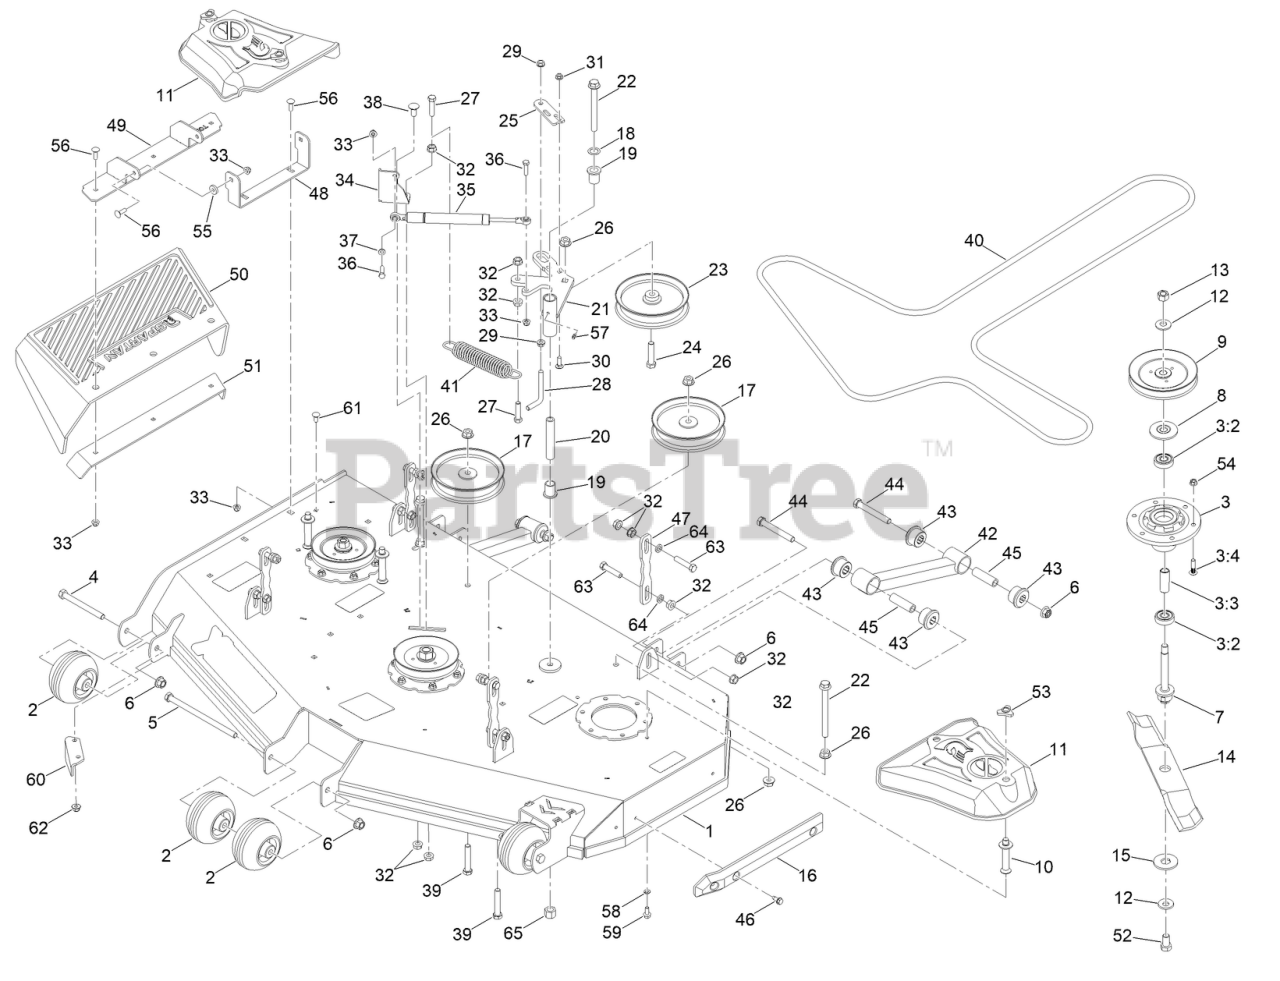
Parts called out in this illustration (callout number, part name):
1	54 INCH DECK ASM W/DECALS
2	MWR ANTI-SCALP WHL W/O GREASE FITTING
3	SPINDLE ASM 5IN DECK
3:2	BEARING
3:3	SPACER, BEARING
3:4	BOLT-ROUND HEAD
4	SCREW-HH
5	1/2-13 X 8-1/2 HEX C/S GR 2 ZINC YELLOW
6	NUT-LOCK
7	SHAFT - SPINDLE
8	GUARD-BEARING TOP 0.673IN
9	PULLEY
10	PIN-BELT COVER
11	COVER BELT
12	M16 SPRING WASHER (39MMOD/ 3.9MM THK)
13	M16X1.5 C8.8 HEX NUT
14	BLADE-ROTARY
15	WASHER-HEX
16	MWR NYLON DECK GUARD
17	6-3/4IN IDLER PULLEY 15/16IN SPACER ASSY
18	.767IDX1.125ODX.016 THK TRIP WV WASHER
19	3/4IN ID X15/16IN OD X 1-1/8IN FLNG BUSH
20	MWR INNER IDLER SPACER
21	MWR DECK IDLER PULLEY ARM ASSY PAINT
22	1/2-13 X 5-1/2 HEX FLANGE BOLT GR 8 ZY
23	6-3/4IN IDLER PULLEY 7/16IN SPACER ASM
24	SCREW-HH
25	DECK IDLER PULLEY BELT RETNR BRKT PAINT
26	NUT-HHF
27	SCREW-HH
28	BOLT-L
29	3/8-16 HEX FLANGE NUT W/SERR ZINC YELLOW
30	BOLT-CARR
32	NUT-HF
33	NUT-HF, NI
34	DECK BELT IDLER DAMPER MTG BRKT PAINTED
35	IDLER GAS SPRING
36	SCREW-HH
37	.312IDX.625ODX.062 THK THRUST BRG OI BRZ
38	SCREW-CARR
39	1/2-13 X 2-3/4 HEX FLANGE BOLT (GR.8) YZ
40	54 DECK BELT
41	MWR DECK SPRING
42	RZ MWR DECK STABLZR ASSY
43	RED A80 SUSP BUSHING
44	1/2-13 X 3-3/4 HEX C/S (GR.5) ZC/YEL
45	UTV A-ARM BUSHING SLEEVE
46	SCREW-HWH, THREAD CUT
47	HANGER-DECK PAINTED GREY
48	BRACKET-CHUTE
49	DECK CHUTE HINGE ASM
50	RZ MWR RUBBER DISCHARGE CHUTE
51	MWR DECK CHUTE HINGE BACKER BRKT
52	M16X1.5-30MM C10.9 HEX BOLT
53	NUT-KNOB
55	.312 ID X .875OD X .1875 THK F/W NYL
56	5/16-18 X 1 CARRIAGE BOLT GR 8 YZ
57	1/4IN DRIVE TYPE GREASE FITTING YZ
58	WASHER-LOCK
59	SCREW-HHF
60	BAFFLE-DISCHARGE
61	SCREW-CARR
62	NUT-HF, NI
63	SCREW-HH
64	.443 ID X .749 OD X .125 THK NYLON BLACK
65	NUT-LOCK, NI
